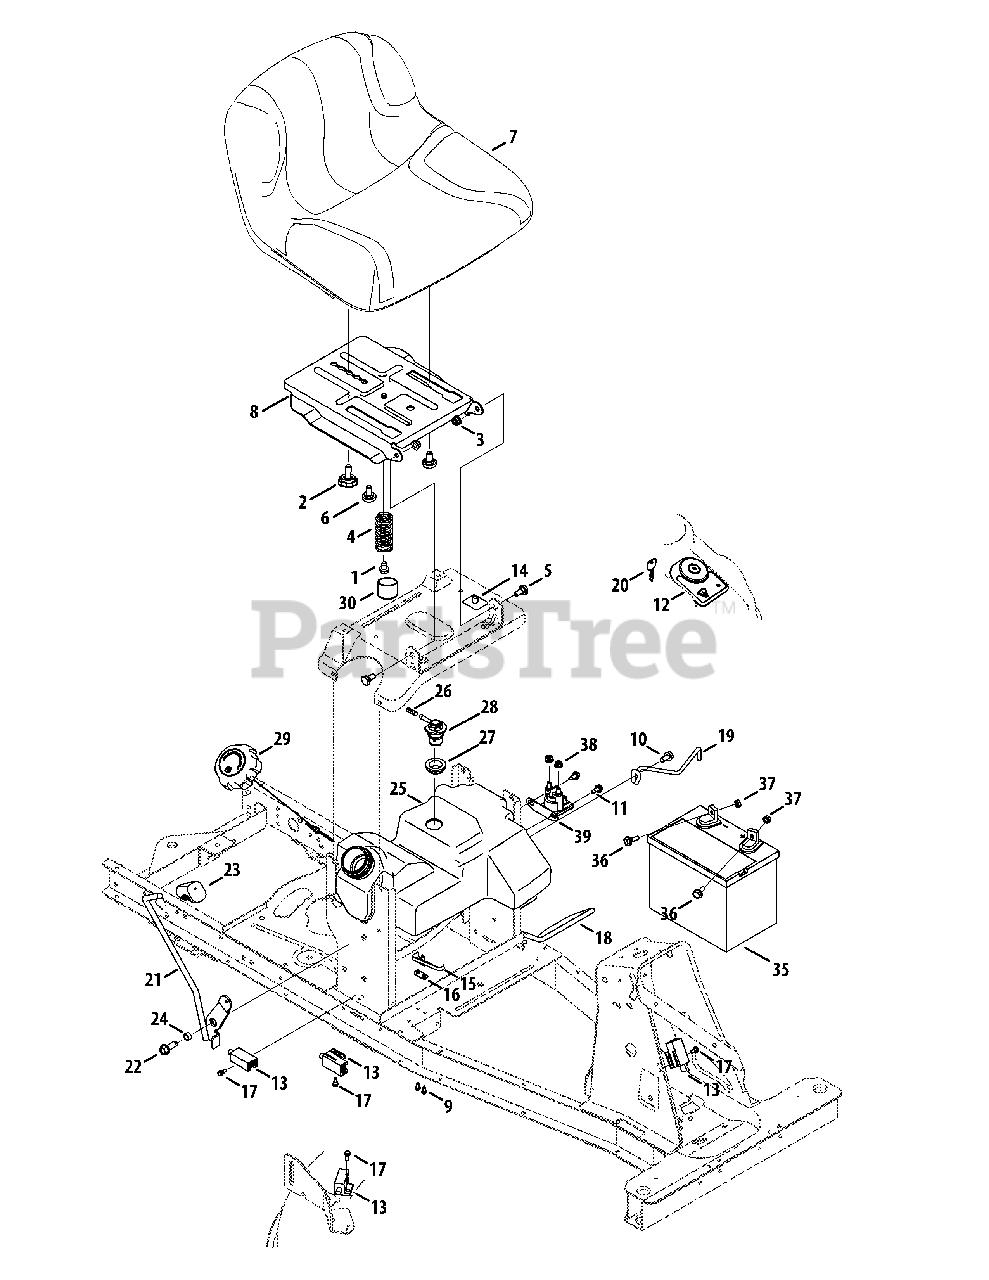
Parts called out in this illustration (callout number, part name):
1	Tap Screw, 5/16-18, 0.500
2	Hex Flange Screw, 3/8-16 x .75
3	Flange Lock Nut, 5/16-18
4	Seat Spring
5	Shldr Spacer, .435 X .178-5/16 X .56
6	Shoulder Screw, .625 x .145, 3/8-16
8	Seat Pivot Bracket
9	Screw, #8
10	Tap Screw, 5/16-18, .750
11	Tap Screw, 1/4-20, .625
12	Key Switch
13	Interlock Switch
14	Seat Switch
15	Switch Spring
16	Insulator Plate
17	Shoulder Screw, #10-32, .500
18	Battery Rod
19	Battery Hold Down Bracket
20	Key, Assembly
21	PTO Handle Assembly
22	Tap Screw, 3/8-16, 1.000
23	Handle Grip, 3/8
24	Spacer, .380 ID x .50 OD x .265
25	Fuel Tank, 1-3 Gal.
26	Hose Vent, 3/16 EPA
27	Rubber Grommet
28	Rollover Valve
29	Fuel Cap
35	Battery, 155 CCA
36	Screw, Shoulder, .250 x .150
37	Nut, Sems, 1/4-20
38	Flange Lock Nut, 1/4-20
39	Solenoid-12 volt
